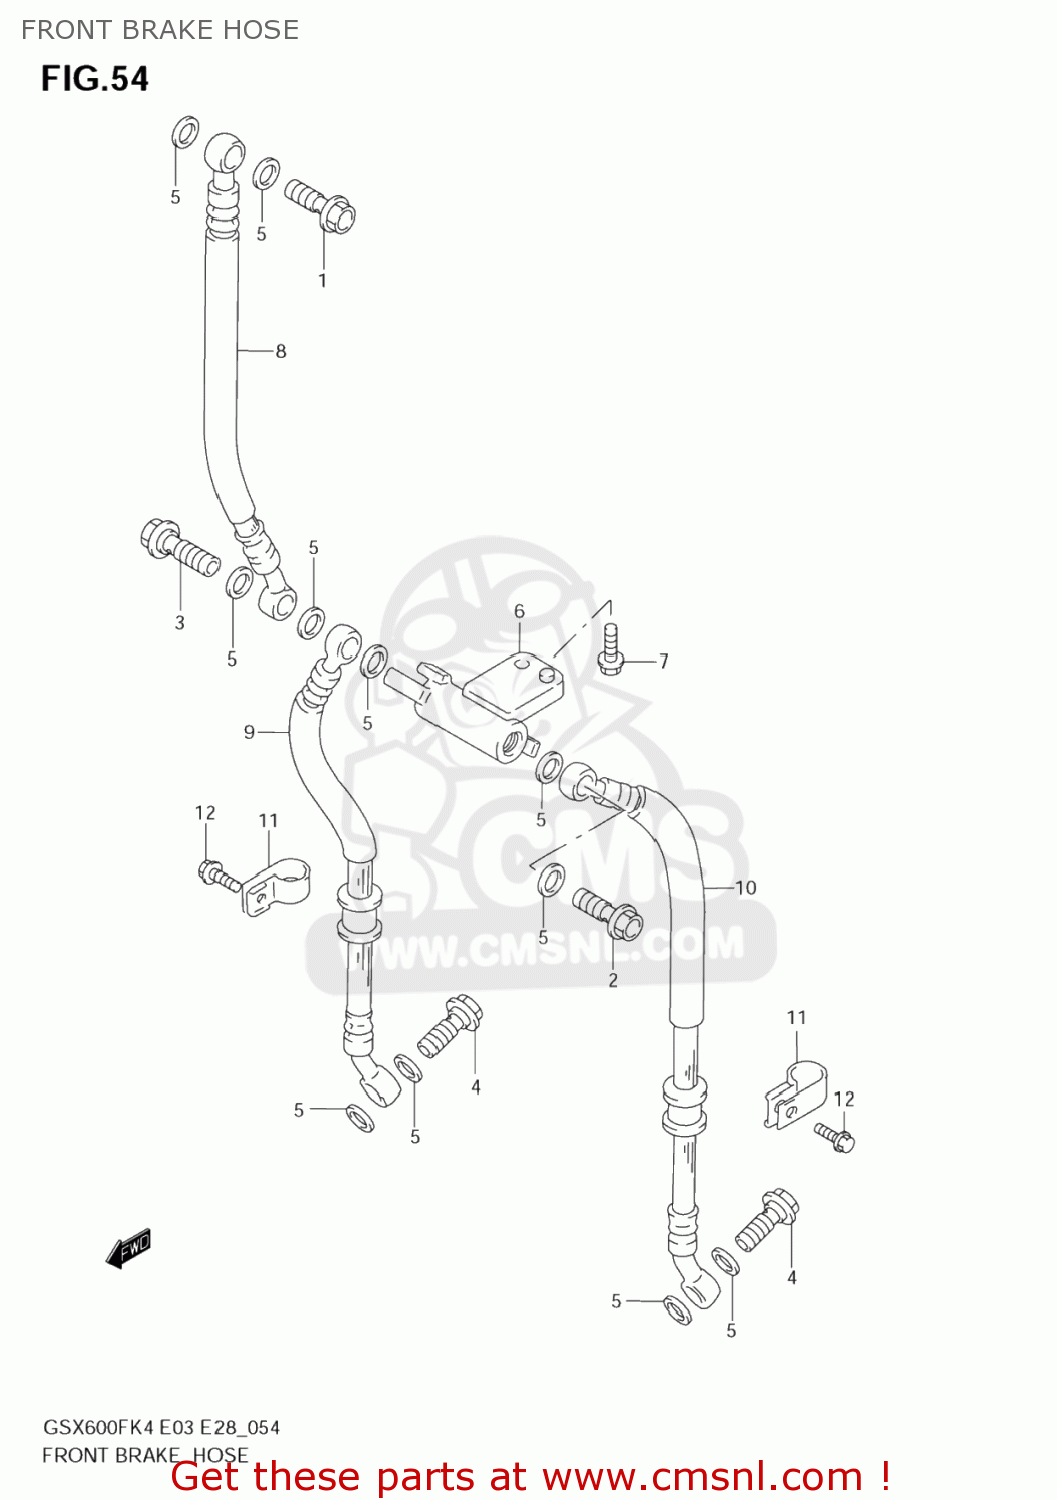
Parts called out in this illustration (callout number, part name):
1	BOLT UNION
2	BOLT UNION
3	BOLT UNION
4	BOLT UNION
5	WASHER(10X15X1.5)
6	JOINT,BRAKE HOSE
7	BOLT
8	HOSE COMP,FRONT BRAKE NO
9	HOSE COMP,FRONT BRAKE
10	HOSE COMP,FRONT BRAKE
11	CLAMP,FR BRAKE HOSE NO.2
12	BOLT
